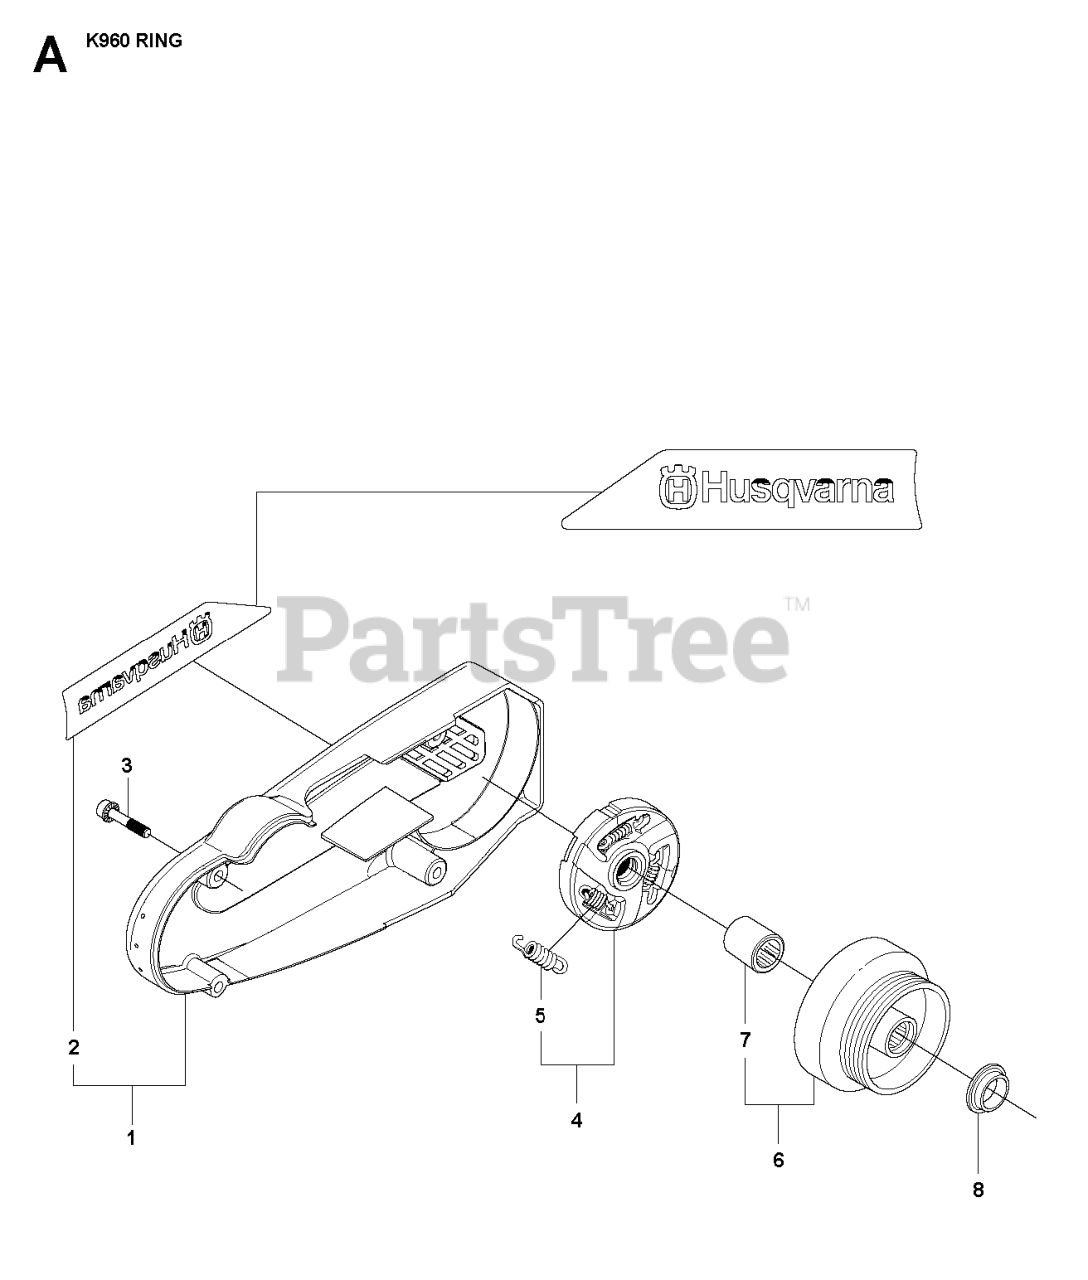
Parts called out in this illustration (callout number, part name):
2	LABEL BELT GUARD
4	CLUTCH COMPLETE
5	CLUTCH SPRING
7	SUPPORT BUSHING
